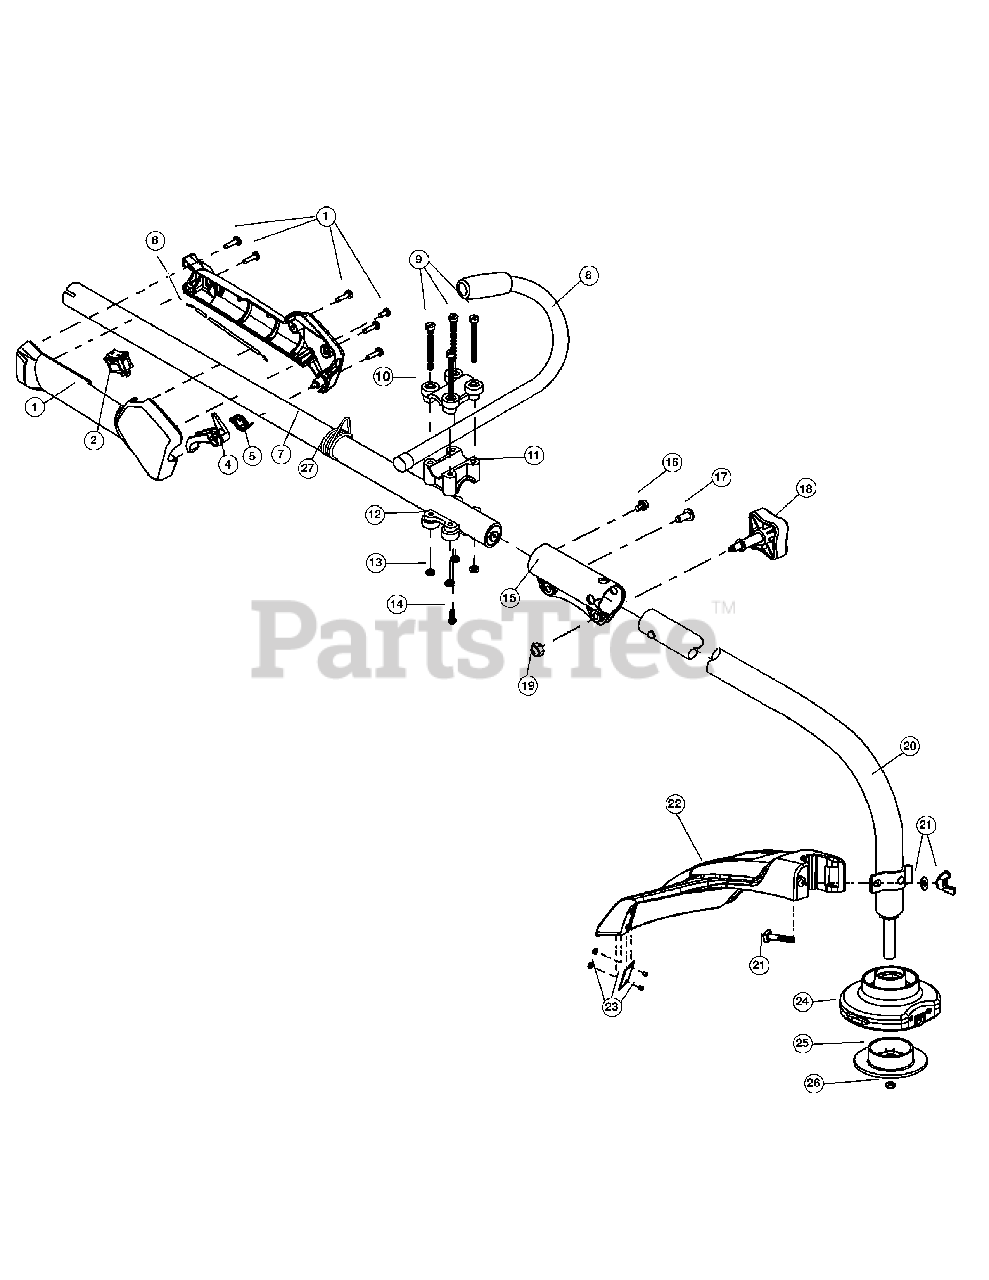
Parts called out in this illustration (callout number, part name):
1	Throttle Housing Assembly (Incl Ref No 2-4)
4	Throttle Trigger
5	Throttle Trigger Spring
6	Throttle Cable
7	Upper Driver Shaft Housing Assembly
8	J-Handle Assembly
10	Upper Handle Clamp
11	Middle Handle Clamp
12	Lower Handle Clamp
14	Anti-Rotation Screw
15	Split Boom Coupler (Incl Ref No 16-19)
18	Adjustment Knob
19	Knob Retaining Nut
20	Lower Driver Shaft Housing Assembly
21	Guard Mounting Hardware
22	Guard Assembly (Incl Ref No 23)
23	Blade Assembly
24	Fixed Line Head Assembly (Incl Ref No 25 & 26)
